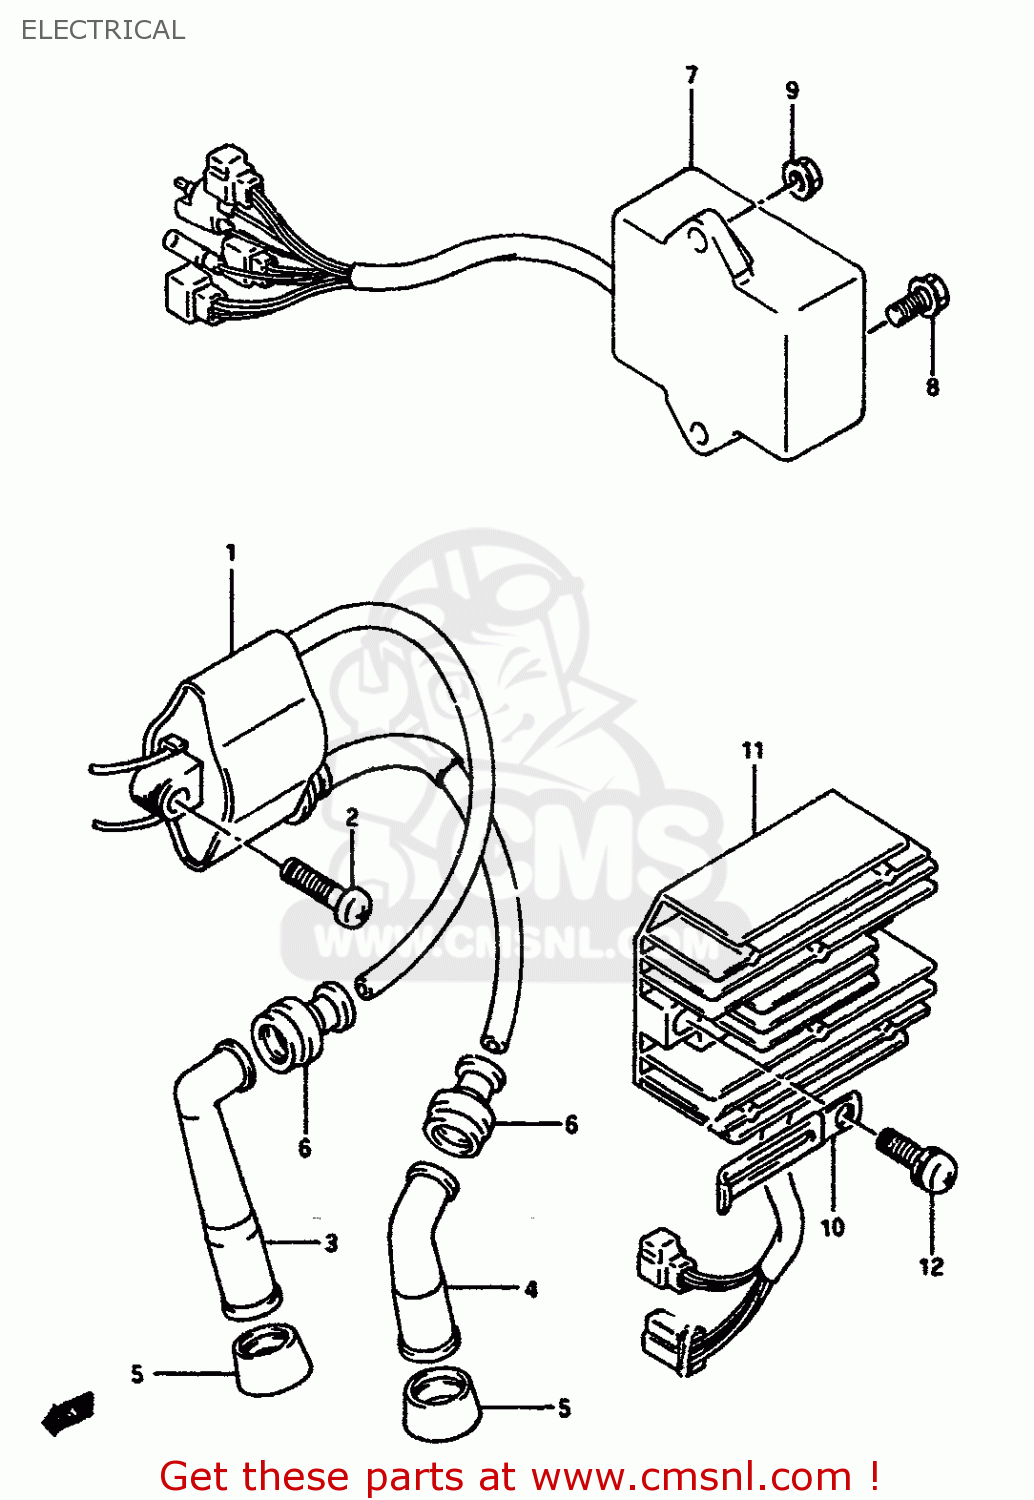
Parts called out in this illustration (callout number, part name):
1	COIL ASSY,IGNITION
2	SCREW
3	CAP ASSY,SPARK PLUG
4	CAP,SPARK PLUG
5	SEAL,SPARK PLUG CAP
6	SEAL,HIGH TENSION CORD
7	CDI UNIT
8	SCREW (6X16) WITH WASHER
9	NUT
10	CLAMP
11	RECTIFIER ASSY
12	SCREW
